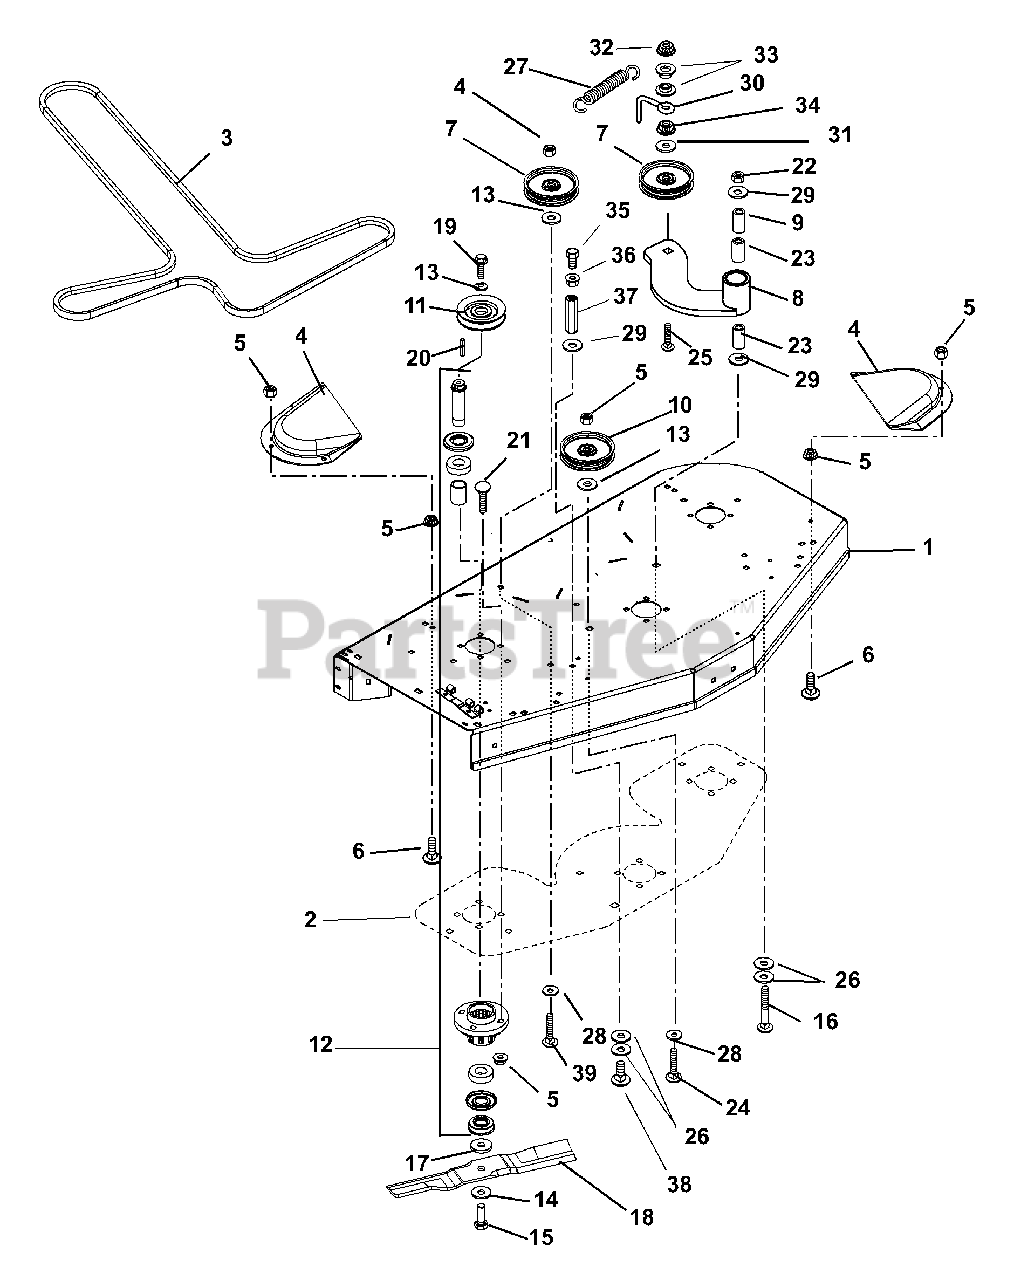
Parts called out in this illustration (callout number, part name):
1	WMT, 40" DECK
1	WMT, 44" DECK
1	WMT, 48" DECK
1	WMT, 52" DECK
2	PLATE, 40" DOUBLER
3	HEX BELT, BB-WRAPPED
3	V-BELT, HA-WRAPPED
3	BELT,HA WRAPPED
5	@NUT-LK-NYL-FLG .38-16 YWZC
6	@BLT-RDHDSQNK .38-16X1.25 G5YZ
7	IDLER, FLAT .38X4.00X1.06
8	WMT, IDLER ARM
9	BSHG, SPCR .502X.997X2.03 PM
10	PULLEY, IDLER 4.00
11	SHEAVE, SPINDLE - 4.00 DIA.
11	SHEAVE, SPINDLE - 4.25 DIA.
11	SHEAVE, SPINDLE - 4.50 DIA.
11	SHEAVE, 4.25 DIA A-SECTION
11	SHEAVE, 4.75 DIA A-SECTION
12	ASSEMBLY, SPINDLE
13	WSHR,FLT STL.406X1.50X.245YWZC
14	WSHR-BLVL .669X1.535X.138
15	BLT-HEX .62-18X1.75 GR8 YWZC
16	@BLT-RDHDSQNK .50-13X3.50 G5YZ
17	WSHR-FLT .640X1.75X.250 YWZC
18	MOWER BLADE, 13.94"
18	BLADE, 15.50"
18	BLADE, MOWER (16.19")
18	BLADE, MOWER (18.00")
18	BLADE, MULCH 15.50"
18	BLADE, MULCH 13.88
19	BLT-HEX .38-16X1.00 YZ GR8
20	KEY, SQ .25 X .38 X .25
21	@BLT-RDHDSQNK .38-16X1.50 G5YZ
22	@NUT-LK-TOP-FLG .50-13 YWZC
23	BRG, 1.00 X 1.12 X .75
24	@BLT-RDHDSQNK .38-16X2.00 G2YZ
25	@BLT-RDHDSQNK .38-16X3.00 G5YZ
26	WSHR-FL-STL.755X1.375X.062YWZC
27	EXTENSION SPRING
28	@WSHR-FL-STL.563X1.38X.109YWZC
29	WSHR-FL-STL .515X1.625X.250 YZ
30	BELT FINGER
31	WSHR-FL-STL .406X1.00X.188 YWZ
32	@NUT-LK-TOP-FLG .38-16 YWZC
33	BSHG-FLG .406X.88X.270X.140
34	NUT-SPIRALOCK-FLG .50-13 PLN
35	@BLT-HEX .50-13X2.00 GR5 YWZC
36	@NUT-HEX .50-13 YWZC
37	NUT, COUPLING 1/2-13X1.75 YWZC
38	@BLT-RDHDSQNK .50-13X1.25 G5YZ
39	@BLT-RDHDSQNK .38-16X2.75 G5YZ
